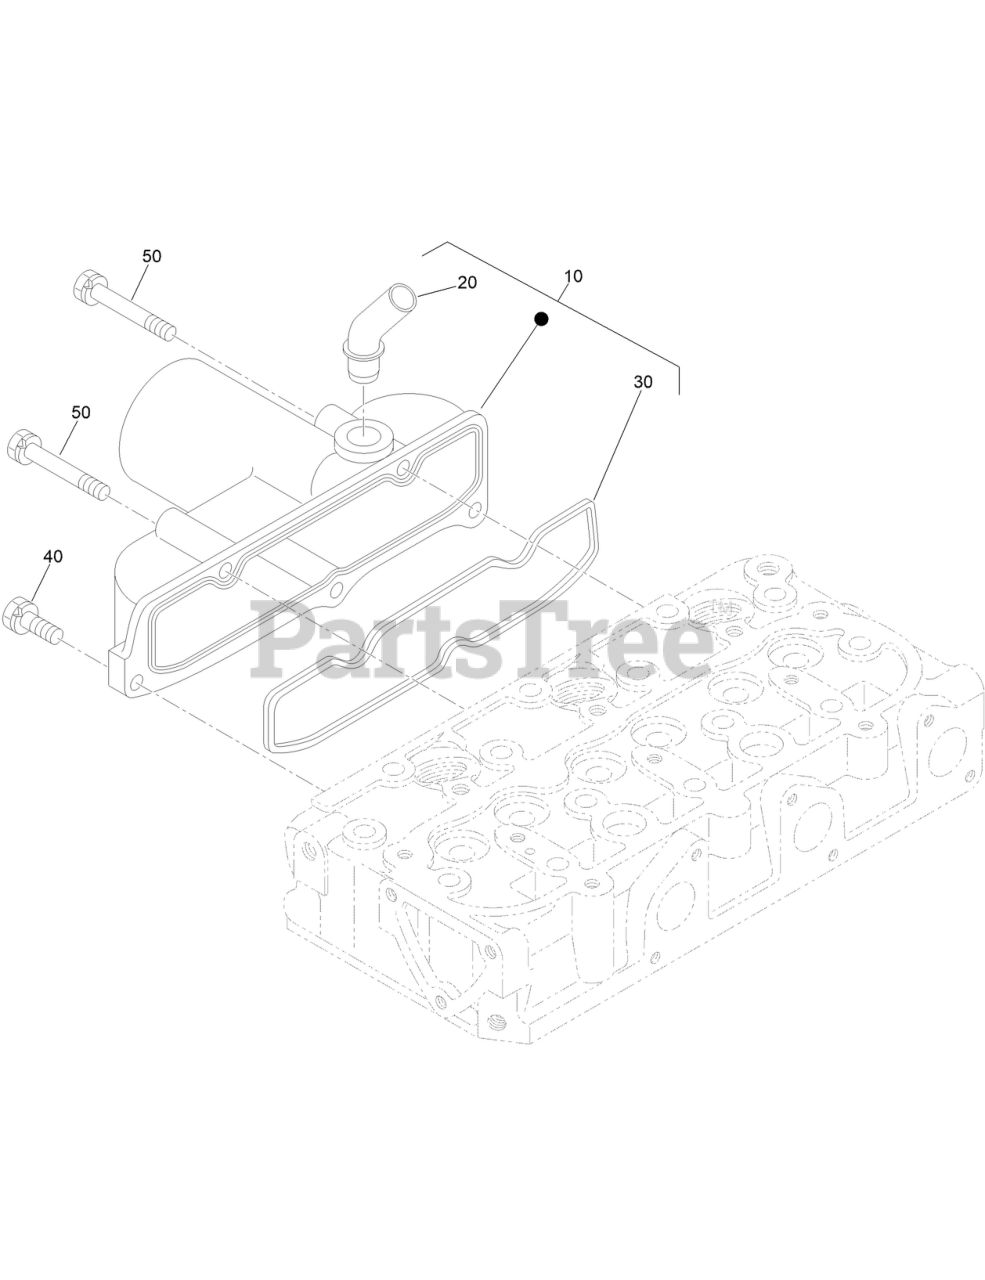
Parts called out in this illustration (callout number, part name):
10	INTAKE MANIFOLD ASM
20	PIPE-BREATHER
30	GASKET-MANIFOLD, INTAKE
40	BOLT-FLANGE
